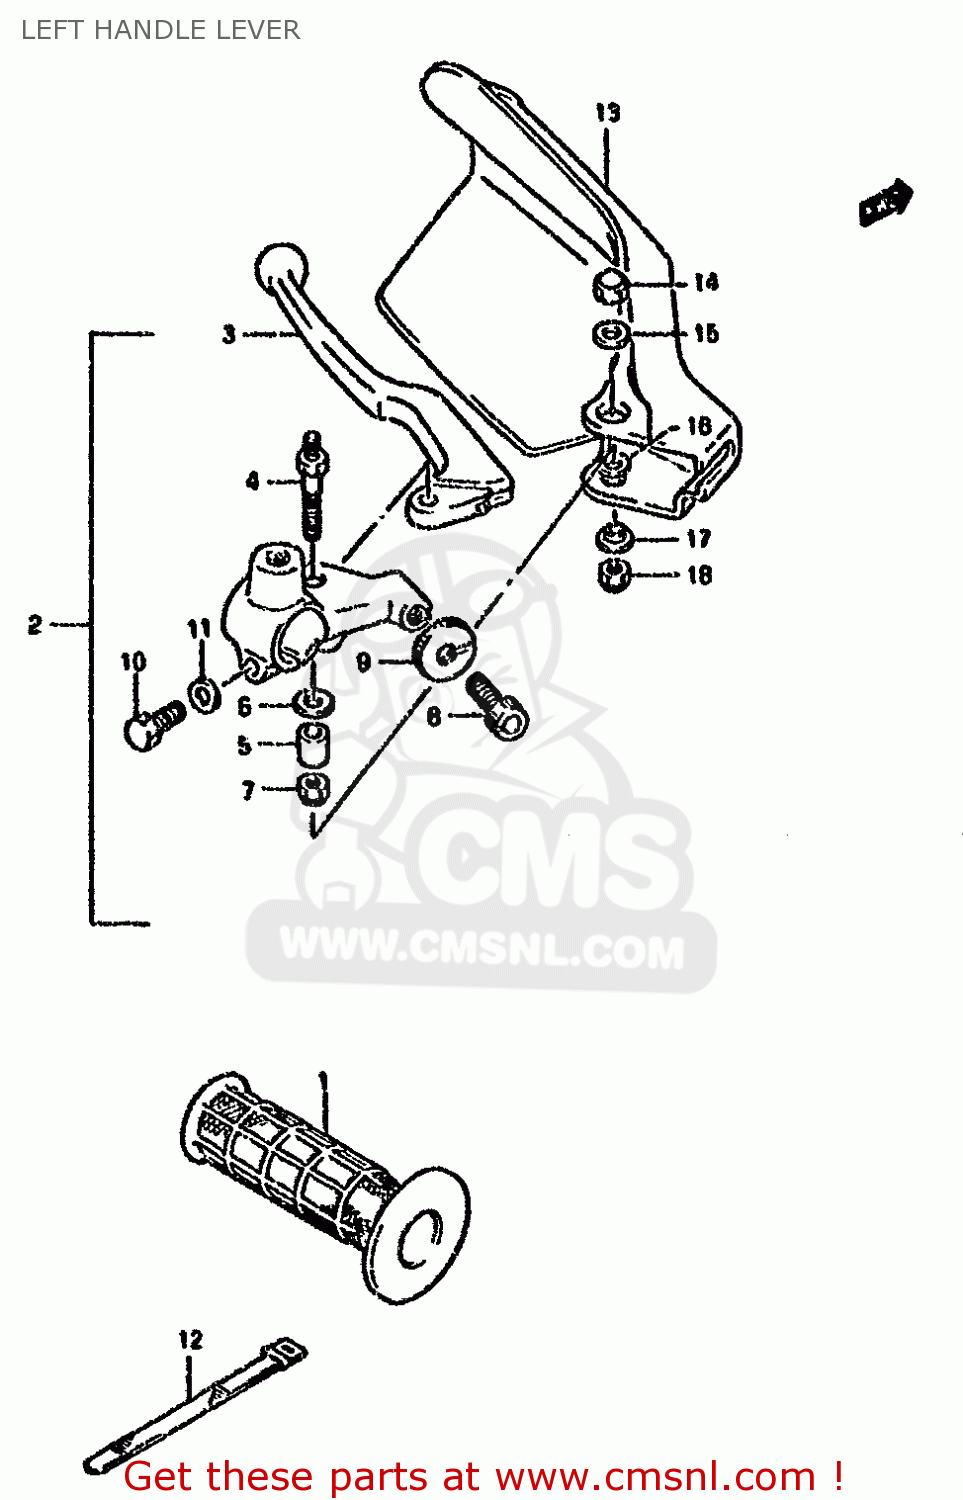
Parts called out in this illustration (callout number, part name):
1	GRIP,L
2	LEVER ASSY,CLUTCH
3	LEVER,CLUTCH
4	BOLT,LEVER SET
5	SPACER,LEVER SET
6	WASHER,LEVER SET
7	NUT
8	ADJUSTER,CABLE
9	NUT,LOCK
10	BOLT
11	WASHER
12	CLAMP(L:120)
13	COVER,KNUCKLE,L
14	NUT
15	WASHER(6.5X20X1.6)
16	WASHER(6.5X16X1.2)
17	WASHER
18	NUT 6MM
